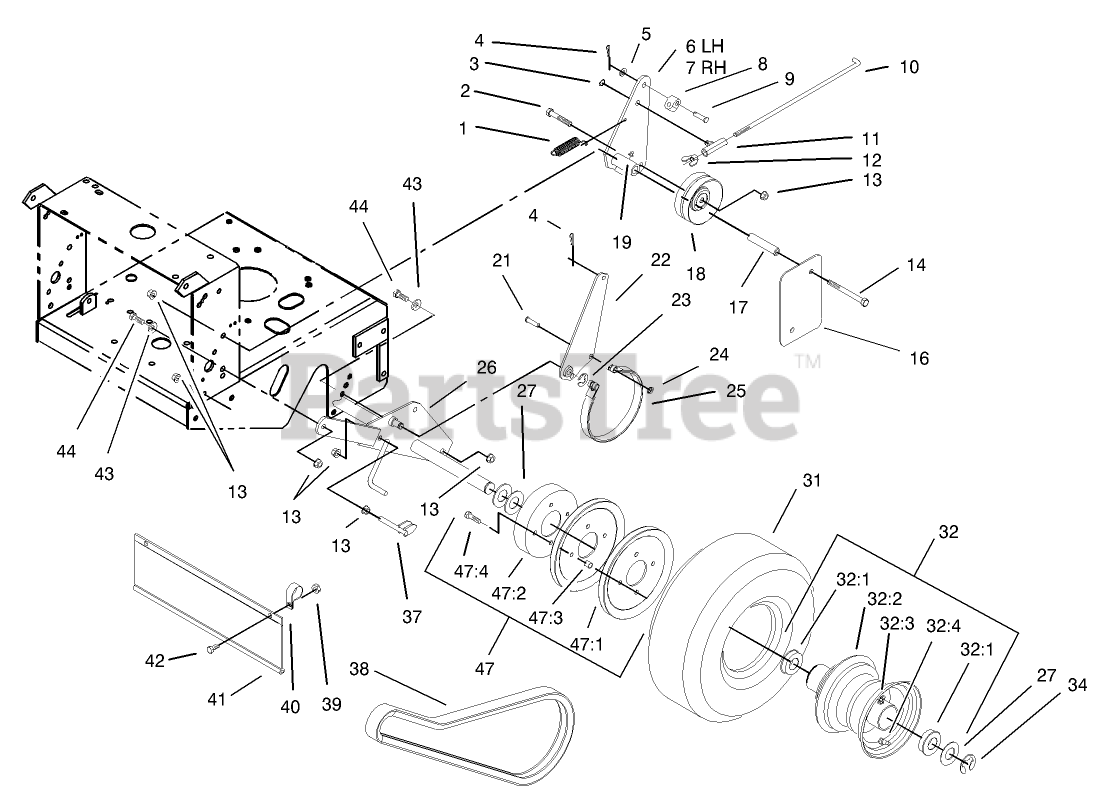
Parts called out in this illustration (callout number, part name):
1	SPRING-EXTENSION
2	SCREW-HH
3	RING-RETAINING
4	PIN-COTTER
5	WASHER-PLAIN
6	RH IDLER ARM ASM
7	LH IDLER ARM ASM
8	FITTING-ROD
9	PIN-CLEVIS
10	ROD-BRAKE
11	SWIVEL-BRAKE
12	WINGNUT-NYLOCK
13	NUT-HHF, WHIZ
14	SCREW-HH
16	SHIELD-WHEEL, DRIVE
17	SPACER-SHIELD
18	IDLER-DRIVE, WHEEL
19	FITTING-GREASE
21	PIN-CLEVIS
22	ARM-BRAKE
23	RING-RETAINING, EXTERNAL
24	NUT-PUSH
25	BAND-BRAKE
27	WASHER-SPACER
28	DRUM-BRAKE
29	SHEAVE-WHEEL, DRIVE
31	Tire-Turfmaster
32	WHEEL AND HUB ASM
32:1	BEARING-FLANGED
32:2	Rim ASM
32:3	Fitting-Grease
32:4	Valve Stem
33	BEARING-FLANGED
34	RING-SNAP
35	SPACER-SHEAVE, WHEEL
36	SCREW-HH
37	SCRAPER
38	V-BELT
39	NUT-LOCK, NI
40	CLAMP-R
41	SHIELD-TRAILING
42	SCREW-HH
43	WASHER-BELLEVILLE
44	SCREW-HH
47	Drive Wheel ASM
47:1	SHEAVE-WHEEL, DRIVE
47:2	DRUM-BRAKE
47:3	SPACER-SHEAVE, WHEEL
47:4	SCREW-HH
